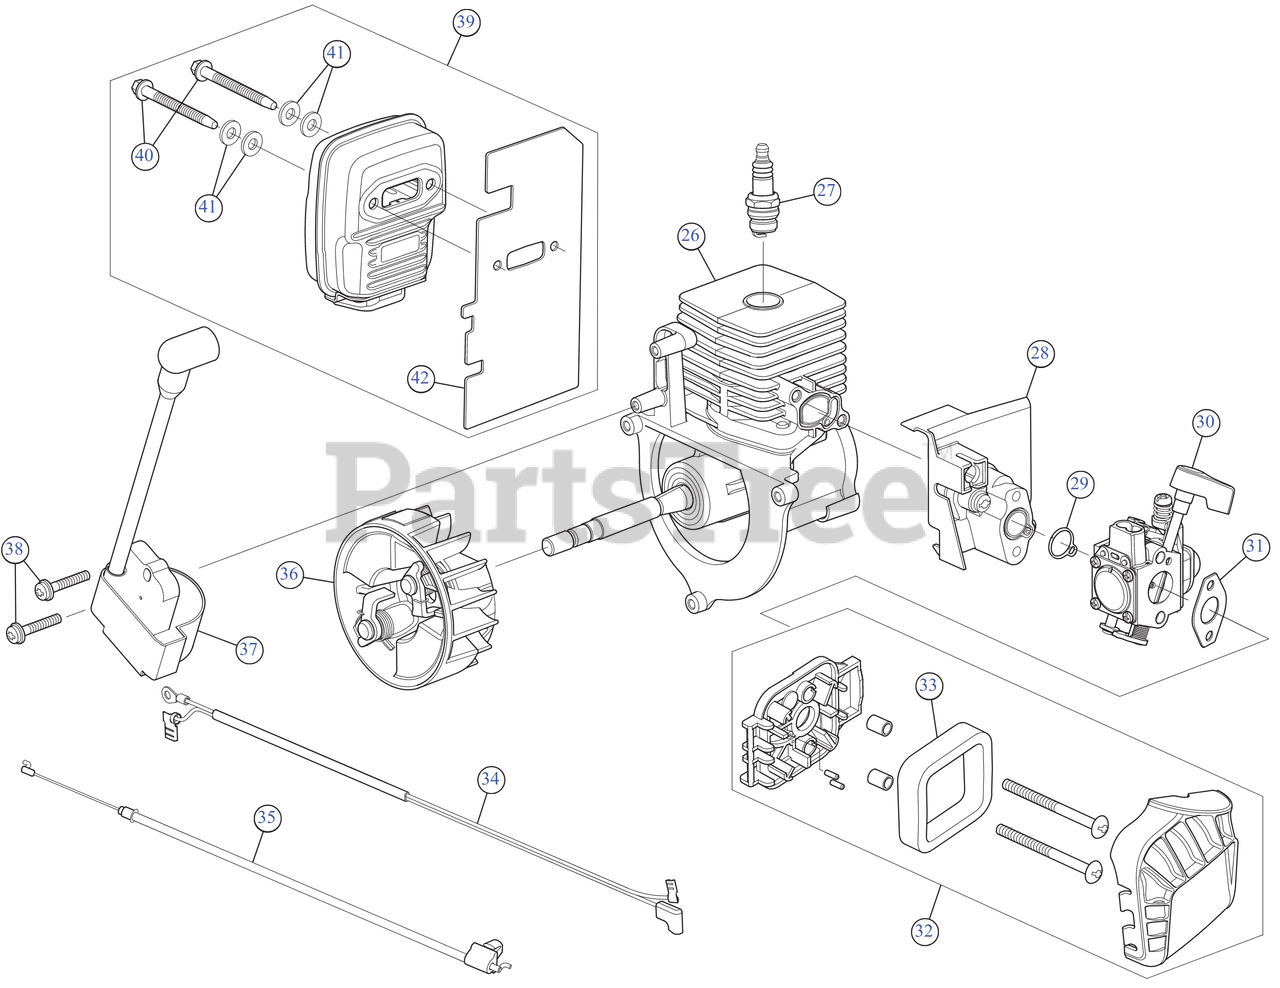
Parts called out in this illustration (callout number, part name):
26	SHORT BLOCK
27	SPARK PLUG
28	INTAKE ASSEMBLY
29	O-RING
30	CARBURETOR
31	GASKET CARB
32	AIRCLEANER ASSEMBLY
33	AIR FILTER
34	WIRE LEAD
35	THROTTLE CABLE
36	FLYWHEEL ASSEMBLY
37	MODULE
38	SCREW 8-32X.750
39	MUFFLER ASSEMBLY
40	MUFFLER SCREW
41	WASH, FLAT .480X.1
42	GASKET
